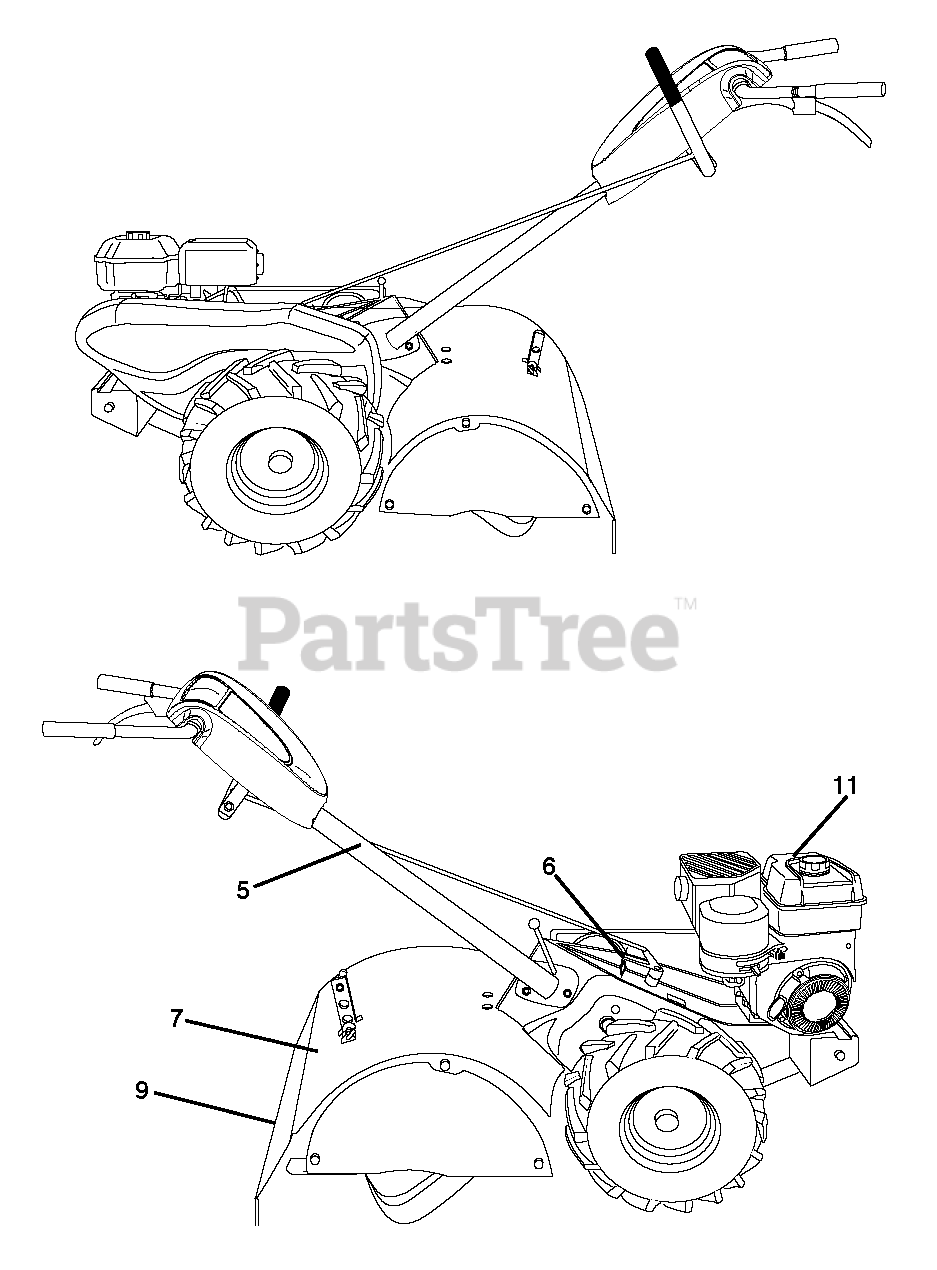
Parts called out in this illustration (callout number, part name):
6	DECAL.SHIFT.INDICATOR.TILLER
7	DECAL WARNING
9	DECAL TI
11	DECAL,ETHANOL E85 WARNING
